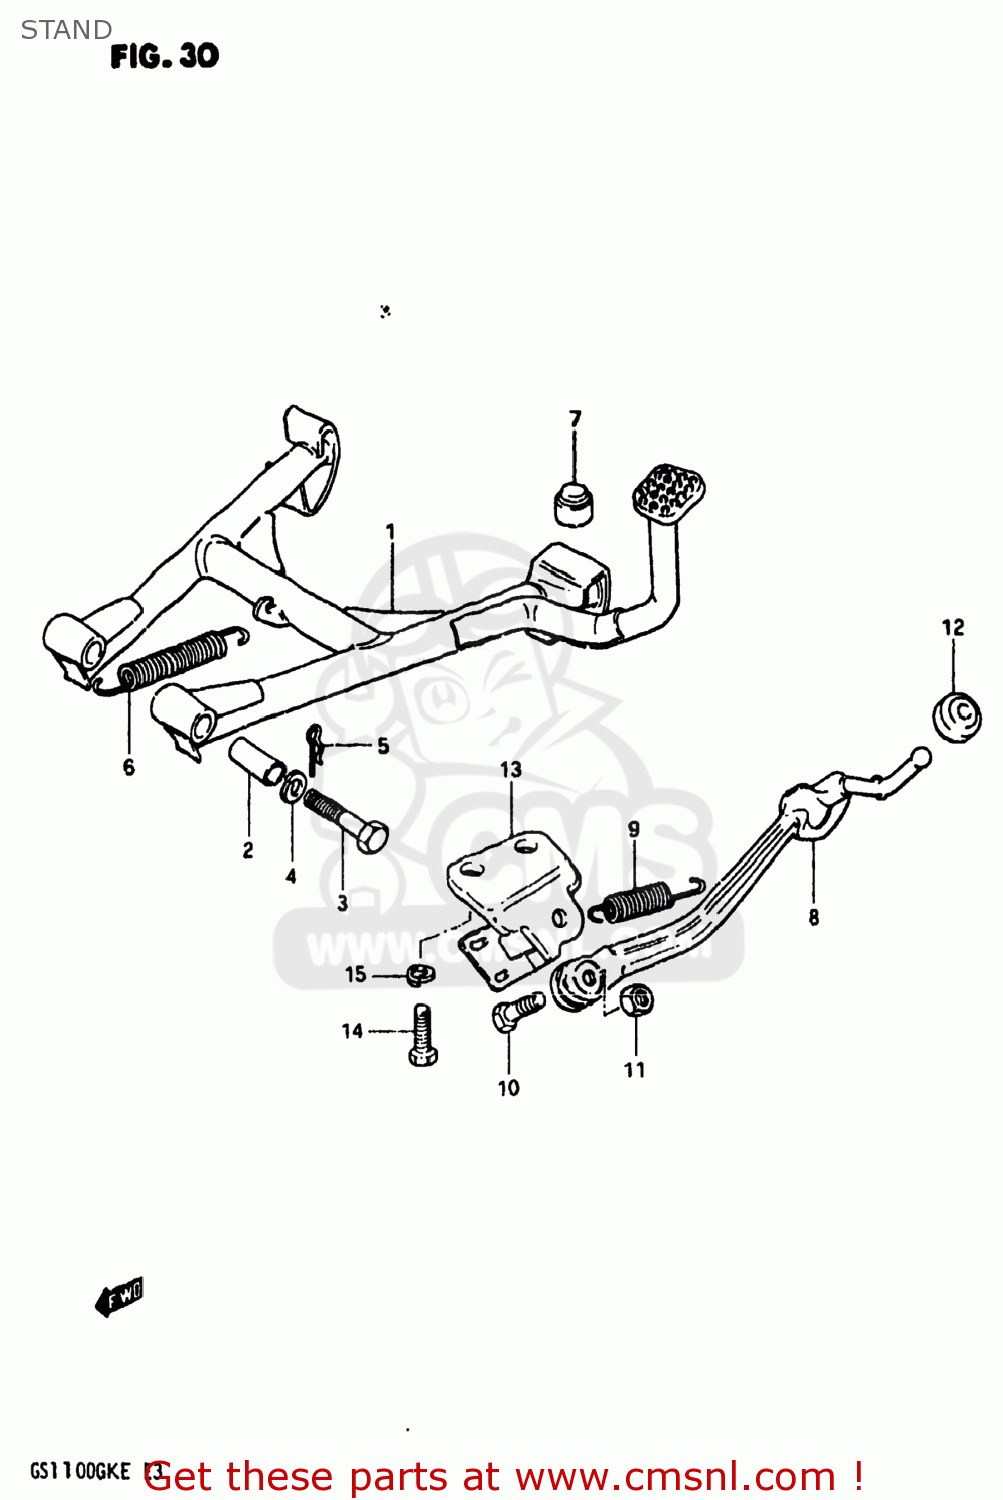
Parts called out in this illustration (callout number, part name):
1	STAND,CENTER
2	SPACER(10X16X38.8)
3	BOLT
4	LOCK WASHER
5	CLIP
6	SPRING
7	CUSHION
8	STAND,SIDE
9	SPRING
10	BOLT(10X34)
11	NUT
12	CUSHION
13	BRACKET,SIDE STAND
14	BOLT
15	LOCK WASHER
